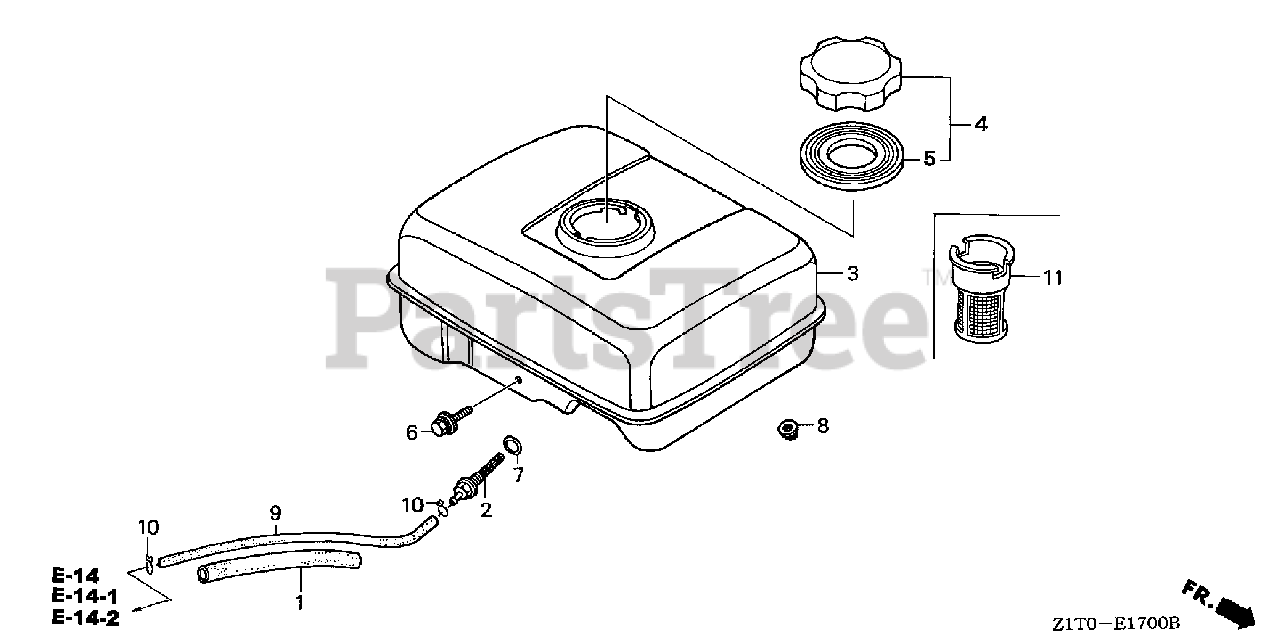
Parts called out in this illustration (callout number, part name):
1	RUBBER, SUPPORTER (107MM)
2	JOINT, FUEL TANK
3	TANK, FUEL *NH31* (MCKINLEY WHITE)
3	TANK, FUEL *NH1* (BLACK)
4	CAP, FUEL FILLER (CHROME PLATED)
4	CAP, FUEL FILLER (CHROME PLATED)(TOUYOUSYA)
5	GASKET, FUEL FILLER CAP (39X62X3) (TOUYOUSYA)
6	BOLT, FLANGE (6X29)
7	O-RING (14MM) (ARAI)
7	O-RING (14MM) (NOK)
8	NUT, FLANGE (6MM)
9	BULK HOSE, FUEL (4.5X3000) (4.5X140)
10	CLIP, TUBE (B8)
